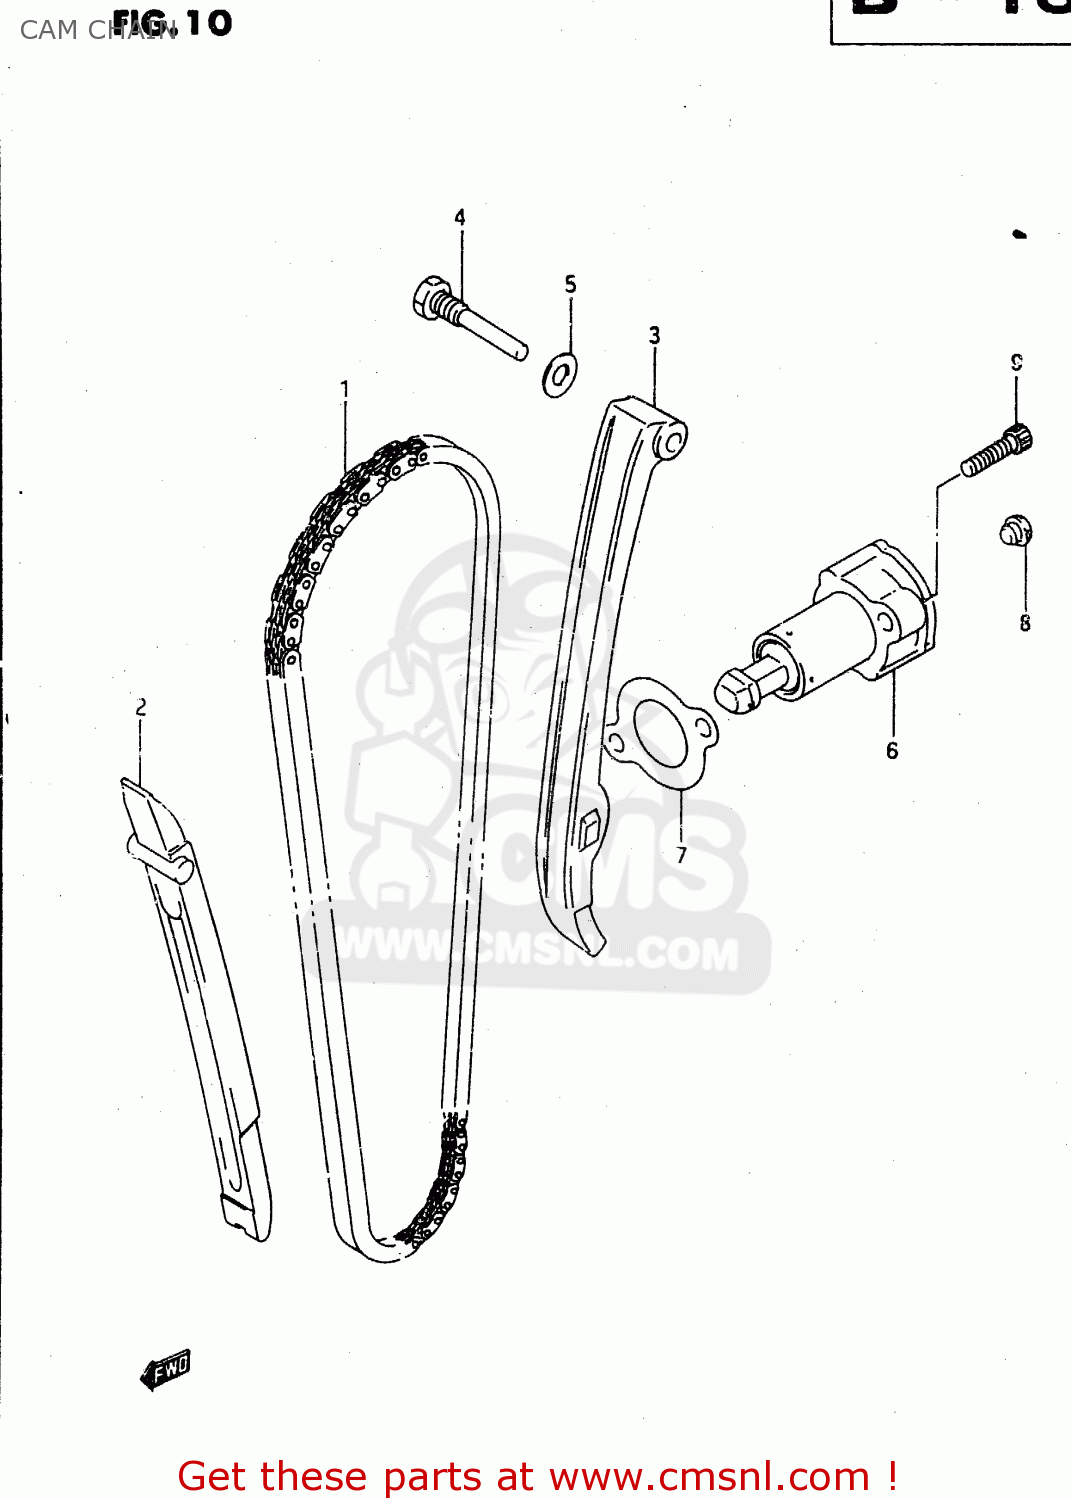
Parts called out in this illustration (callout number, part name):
1	CHAIN,CAMSHAFT DRIVE
2	GUIDE,CAM CHAIN
3	TENSIONER,CAM CHAIN
4	BOLT,CAM CHAIN TENSIONER
5	GASKET 8.2X14X1 (NAS)
6	ADJUSTER ASSY,TENSIONER
7	GASKET,TENSIONER ADJUSTER (NAS)
8	PLUG,ADJUSTER
9	BOLT,CL.COVER
